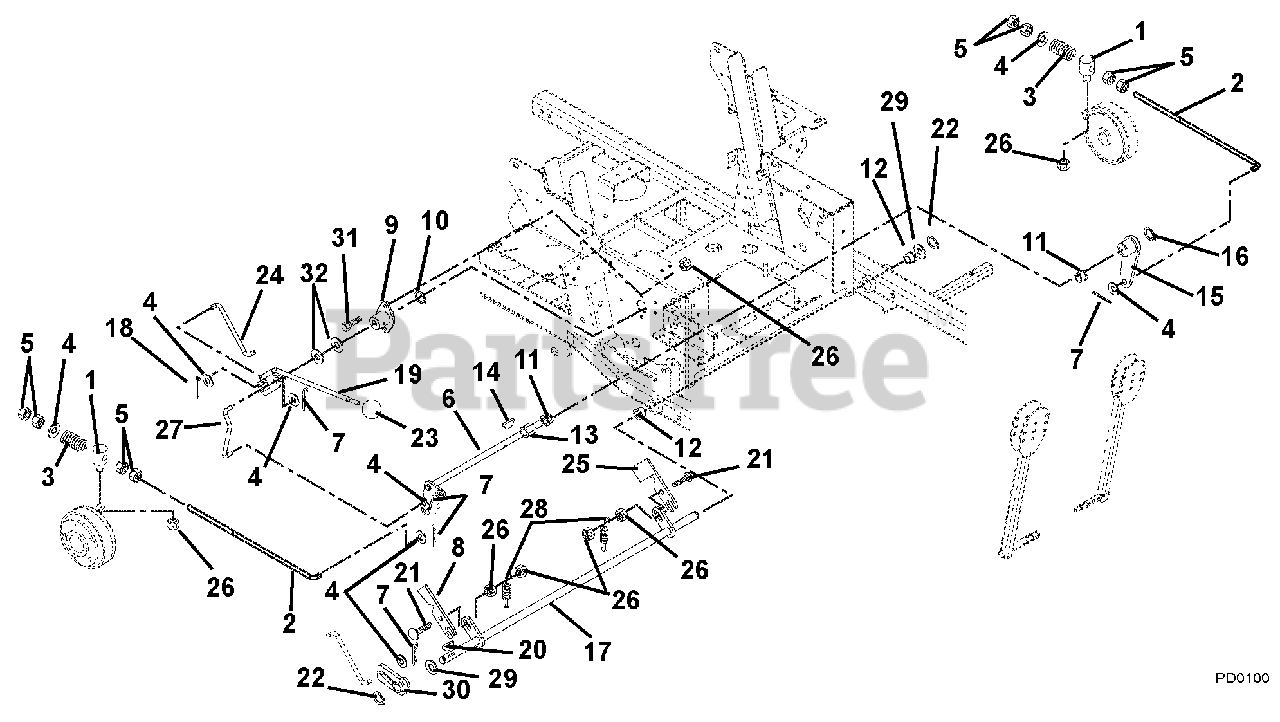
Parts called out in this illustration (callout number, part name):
1	Pivot, Brake Rod
2	Rod, Brake .38 x 19.00
3	Spring, Compression .142 x .710 x 1.75
4	Washer, Flat Steel .406 x .812 x .065
5	Nut, Hex .38-16
6	Shaft, Brake Cross
7	Pin, Hair
8	Slide, Interlocking Brake
9	Bushing, Flange
10	Ring, Retaining External .625 x .05
11	Bushing, Flange Nylon .762 x 1.00 x .58 x 1.48
12	Bushing, Flange .515 x .75 x .745 x 1.00
13	Bushing, Sleeve .75 x 1.00 x .75
14	Key, Woodruff .19 x .75 Hard #9
15	Weldment, Brake Arm
16	Ring, Retaining External .689 x .078
17	Weldment, Mechanical Brake
18	Pin, Cotter External .09 x .75
19	Weldment, Brake Actuating
20	Key, Woodruff .13 x .63
21	Bolt, Round Head Square Neck .31-18 x 1.25 Grade 5
22	Ring, Retaining External .50 x .05
23	Knob, Steering Lock
24	Linkage, Brake Actuating
25	Interlock, Safety Switch
26	Nut, Locking Top Flange .31-18
27	Linkage, Brake Actuating
28	Spring, Tension .063 x .44 x 1.56
29	Washer, Flat Steel .505 x 1.00 x .062
30	Weldment, Parking Brake Hub
31	Bolt, Hex .31-18 x .75 Grade 5
32	Brake, Left Hand Caliper
